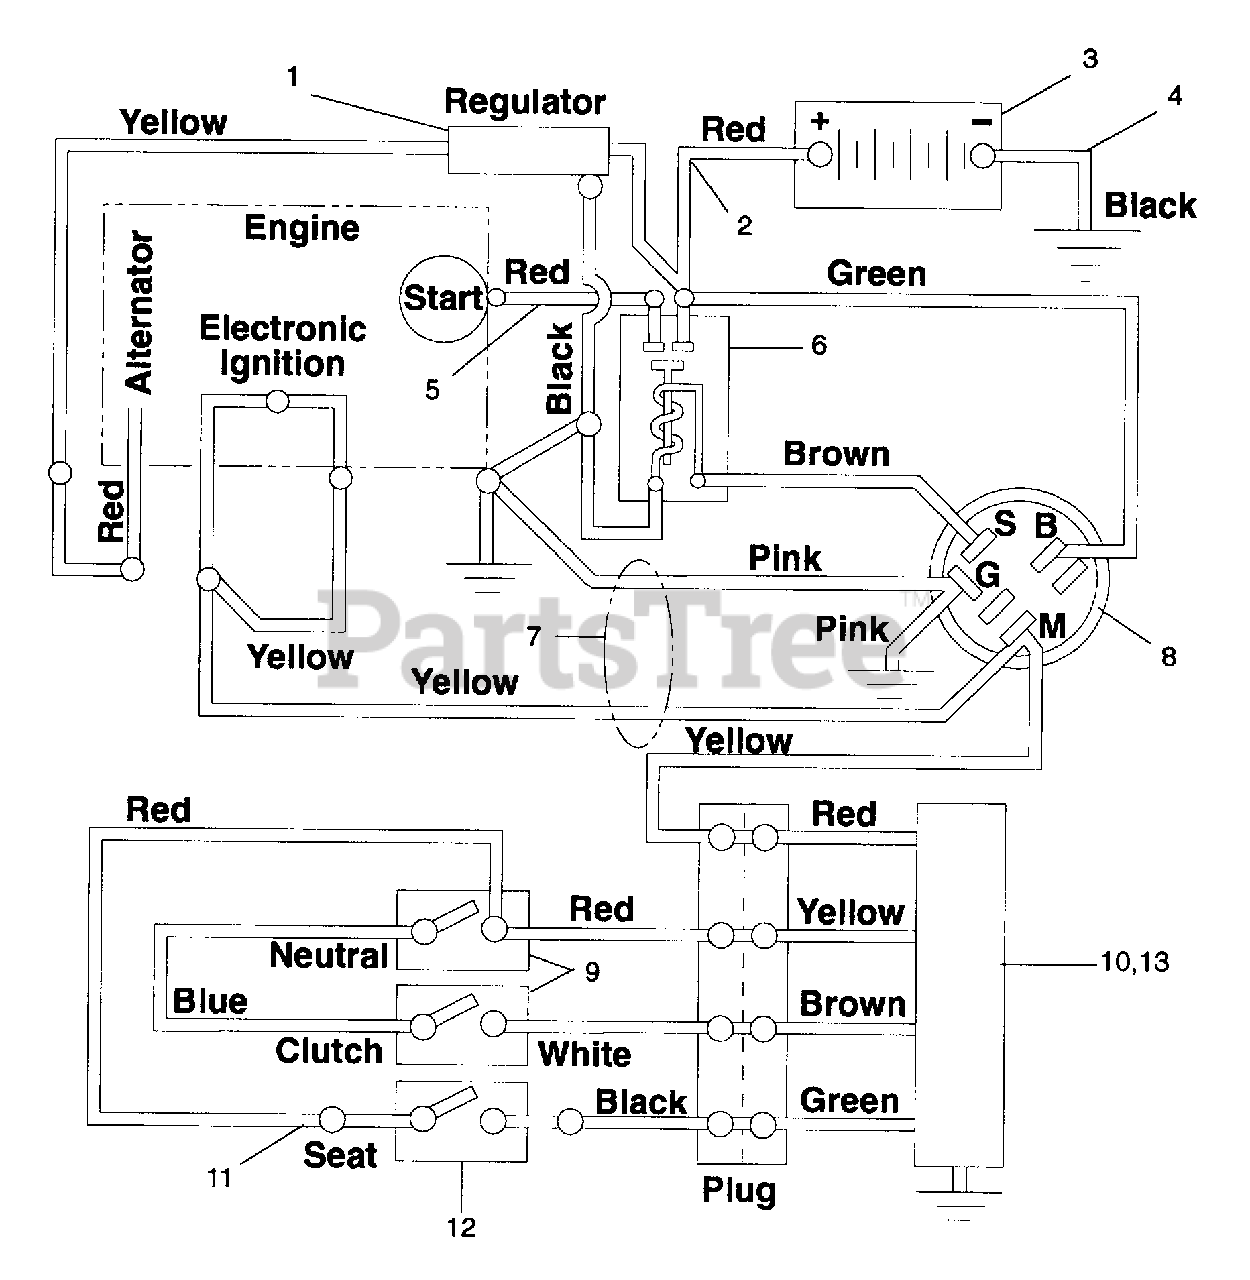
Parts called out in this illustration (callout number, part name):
1	REGULATOR
2	STARTER CABLE 16"
3	BATTERY
4	GROUND CABLE .25X13.00X.31
5	STARTER CABLE 13"
6	SOLENOID
7	WIRE HARNESS RM B&S ENGINES
8	SWITCH ASSEMBLY
9	SWITCH- SNAP MTG N.O.
10	MODULE,INTERLOCK,RECOIL, 1201
11	ADAPTER - SEAT SWITCH
12	SWITCH SEAT
13	HARNESS ADAPTER
